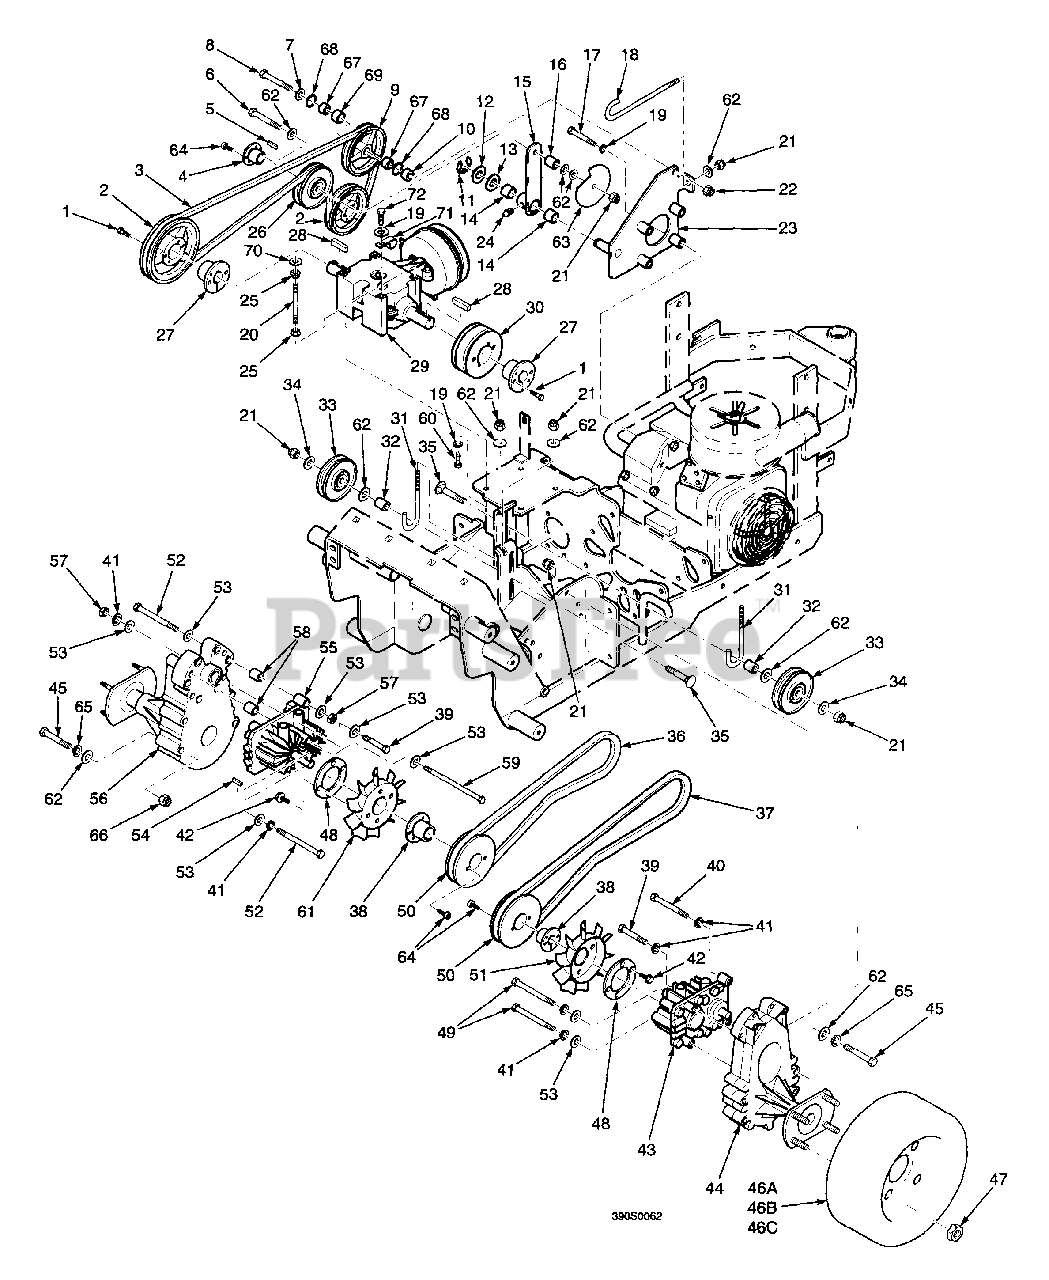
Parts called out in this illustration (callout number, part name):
1	Bolt, Hex Head, 1/4-20 x 1-3/8"
2	Pulley, 5.55 OD
3	Belt, Main Drive
4	Hub, Tapered
5	Key, 1/4 x 1/4 x 1-1/2"
6	Bolt, Hex Head, 3/8-16 x 3-1/4"
7	Flatwasher, 1/2 (.531 x .062 x 095)
8	Bolt, Hex Head, 1/2-13 x 3-1/4"
9	Pulley, Idler - 5.75 Dia
10	Spacer
11	Retaining Ring, .75 "E"
12	Flatwasher, 3/8 (7.66 x 1.25 x .06)
13	Flatwasher, 3/8 (7.66 x 1.25 x .035)
14	Bushing, Oilite, .753 ID
15	Arm, Idler
16	Spacer, J-Pull Rod
17	Bolt, Hex Head, 3/8-16 x 2-3/4"
18	Rod, J-Pull
19	Lockwasher, 3/8"
20	Stud, 3/8-16 x 4.00"
21	Hex Locknut, Elastic Stop, 3/8-16
22	Hex Locknut, Elastic Stop, 1/2-13
23	Pivot, Engine Idler
24	Grease Fitting
25	Serr. Fl. Hex Nut, 3/8-16
26	Pulley, Idler
27	Hub, Tapered, 1.00 Bore
28	Key, 1/4 x 1/4 x 1-1/4"
29	Gearbox, T-Drive
30	Pulley, 4.25 OD Double Groove
31	Rod, J-Pull
32	Spacer, J-Pull
33	Pulley
34	Flatwasher, 3/8 (.375 x 1.50 x .06)
35	Carriage Bolt, 3/8-16 x 2-1/2"
36	Belt, R.H. Transmission Drive
37	Belt, L.H. Transmission Drive
38	Hub, Tapered, 15 mm
39	Bolt, Hex Head, 5/16-18 x 1-3/4"
40	Bolt, Hex Head, 5/16-18 x 2-1/2"
41	Lockwasher, 5/16"
42	Serr. Fl. Hex Head CPSCR, 1/4-20 x 1/2"
43	Pump, L.H.
44	Axle, L.H.
45	Bolt, Hex Head, 3/8-24 x 4.0 GR 8
46A	Wheel Assembly, Drive
46B	Tire Only
46C	Rim Only
47	Nut, Wheel
48	Back-up Washer, Fan
49	Bolt, Hex Head, 5/16-18 x 5-1/2"
50	Pulley, 4.25 OD
51	Fan, Cooling LH
52	Bolt, Hex Head, 5/16-18 x 4-1/2"
53	Flatwasher, 5/16 (.344 x .688 x .065)
54	Key, 5 mm x 5 mm x 25 mm
55	Pump, R.H.
56	Axle, R.H.
57	Hex Nut, 5/16-18
58	Spacer
59	Bolt, Hex Head, 5/16-18 x 7-1/2"
60	Bolt, Hex Head, 3/8-16 x 1-1/4"
61	Fan, Cooling RH
62	Flatwasher, 5/16 USS GR 8
63	Washer, Heat Deflector
64	Socket Head Capscrew, 1/4-20 x 1-3/8"
65	Lockwasher, 3/8 Spring, Hardened
66	Lock Nut 3/8-24 Elastic Stop GR 8
67	Bearing Idler Pulley
68	1.575" Truarc Ring
69	Sleeve, Idler Pulley
70	Flatwasher, 3/8 (.391 x .938 x .105)
71	Clamp, .75 ID
72	Hex Head Bolt, 3/8-16 x 3/4"
